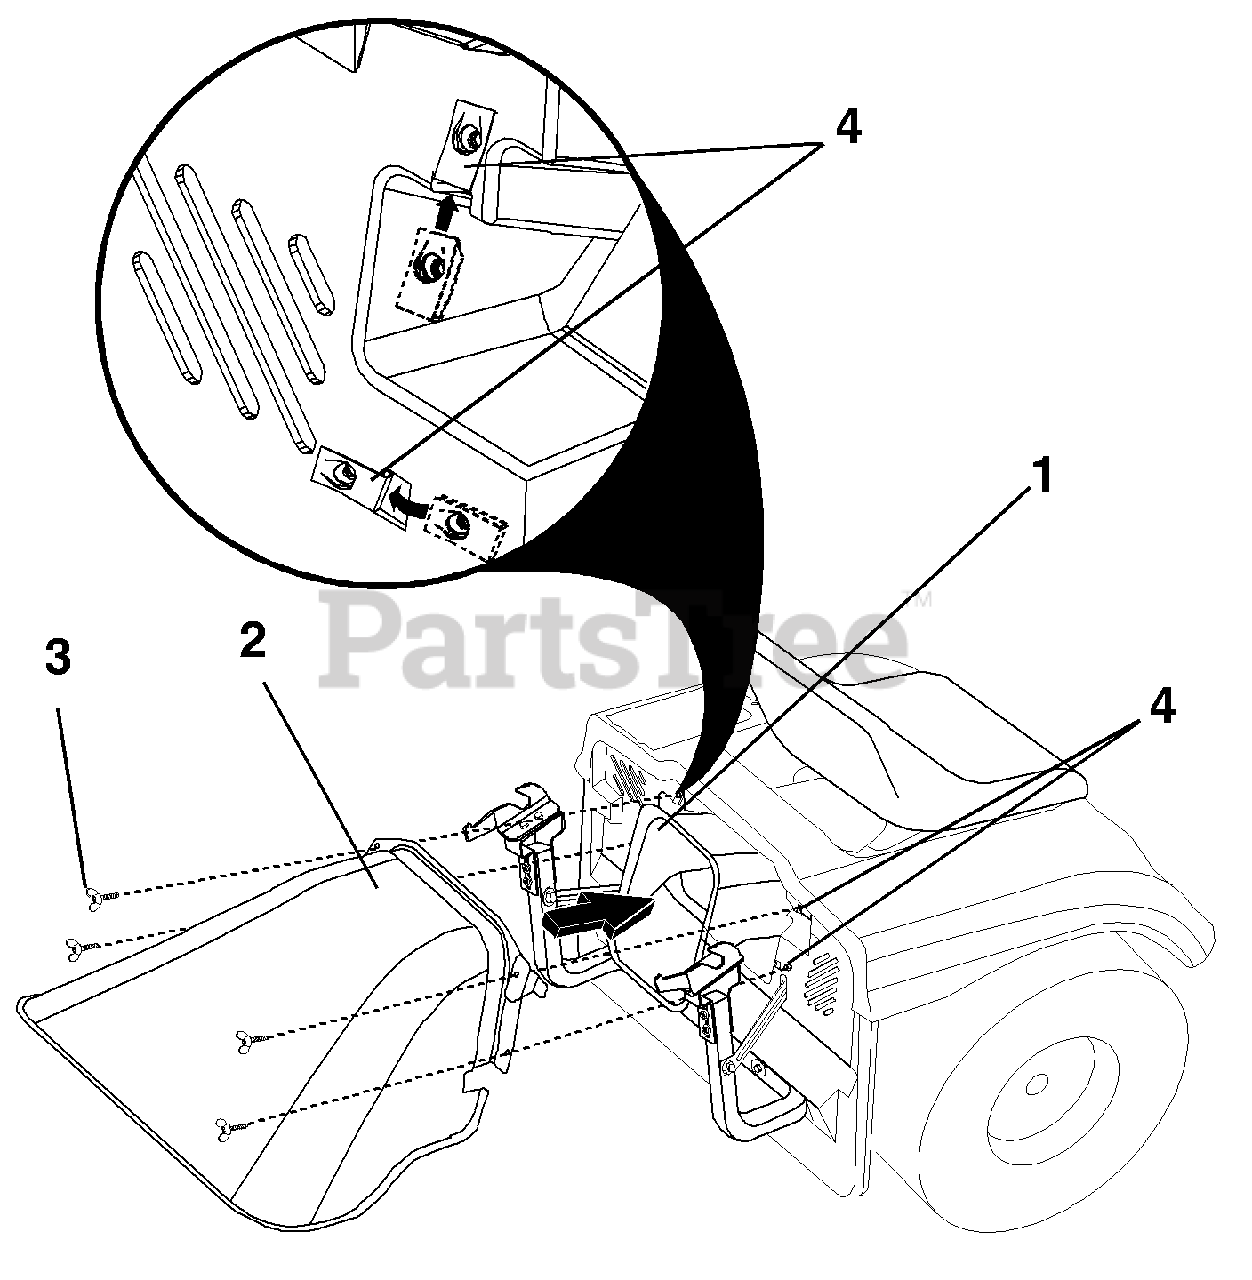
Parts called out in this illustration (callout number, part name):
1	Discharge Chute
3	Wing Screw
4	Threaded Insert
